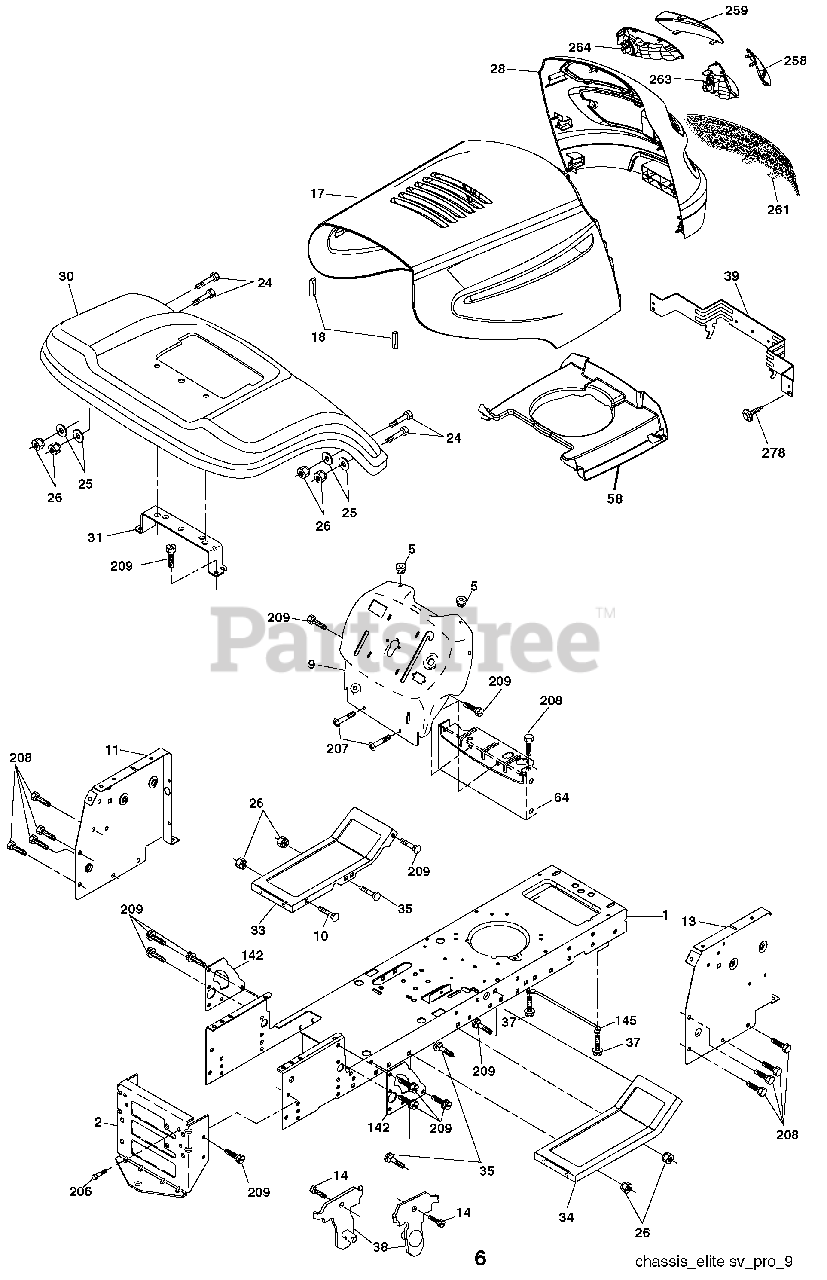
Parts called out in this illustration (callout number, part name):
1	Chassis
2	Drawbar, Stretch
5	Bumper, Hood/Dash
9	Dash
10	Bolt, Carriage 3/8-16 x 1
11	Panel Dash LH
13	Panel Slkscr Dash RH
14	Screw Thdrol 3/8-16 x 1/2
17	Hood
18	Bumper Hood
24	Bolt Fin Hex 3/8-16 unc x 1 Gr. 5
25	Washer 13/32 x 13/16 x 12 Ga.
26	Nut Lock Hex w/Ins 3/8-16 unc
28	Grille/Lens Asm.
30	Fender
31	Bracket Fender Repl 109873X
33	Footrest Pnt LH
34	Footrest Pnt RH
35	Bolt Rdhd Sht Sqnk 3/8-16 x 3/4
37	Screw Thdrol 5/16-18 x 1/2 TYT
38	Bracket Asm. Pivot Mower
39	Bracket Pivot
58	Duct Intake
64	Dash Lower
142	Plate Reinforcement
145	Rod Pivot Chassis/Hood
206	Bolt Shoulder 5/16-18
207	Screw 5/16-18 x 1/2
208	Screw Thdrol 3/8-16 x 1/2
209	Screw Hex Wsh Thdrol 3/8-16
258	Lens Grille RH
259	Lens Grille LH
263	Bezel Grille RH
264	Bezel Grille LH
278	Screw 10 x 3/4 Single Lead Hex
278	Plug Button Blk 359 Dia Choke
278	Plug Dome Plastic
